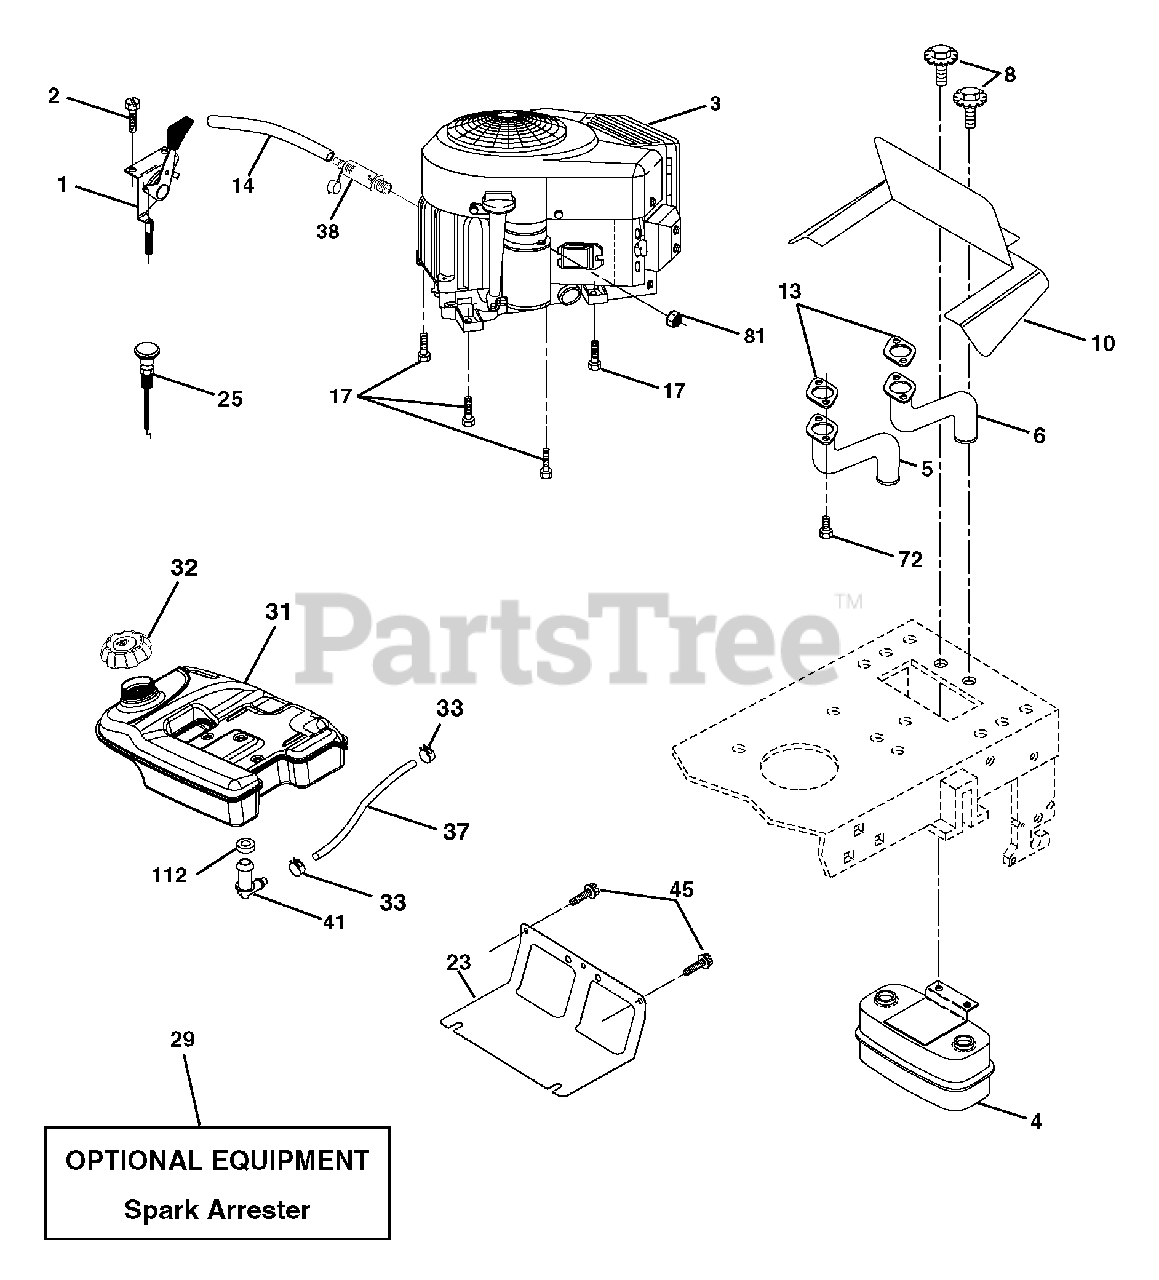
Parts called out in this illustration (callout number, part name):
1	Control, Throttle/Choke
2	Screw Hex Single Lead 10 x 3/4
4	Muffl er
5	Tube Exhaust LH
6	Tube Exhaust RH
8	Bolt 5/16-18 unc x 3/4 w/Sems
10	Shield Heat Muffl er
13	Muffl er Gasket
14	Tube Oil Drain
17	Screw 3/8-16 x 1-1/2
23	Shield, Browning/Debris Guard
29	Arrester, Spark
31	Tank, Fuel
32	Cap Gauge, Fuel
33	Clamp, Hose Blk
37	Line, Fuel
38	Plug Drain Oil Easy
41	Stem Tank Fuel
45	Screw Hex Wsh Thdrol 3/8-16 x 3/4
72	Screw 5/16-18 x 1
81	Nut Keps Hex 1/4-20 unc
112	Bushing
